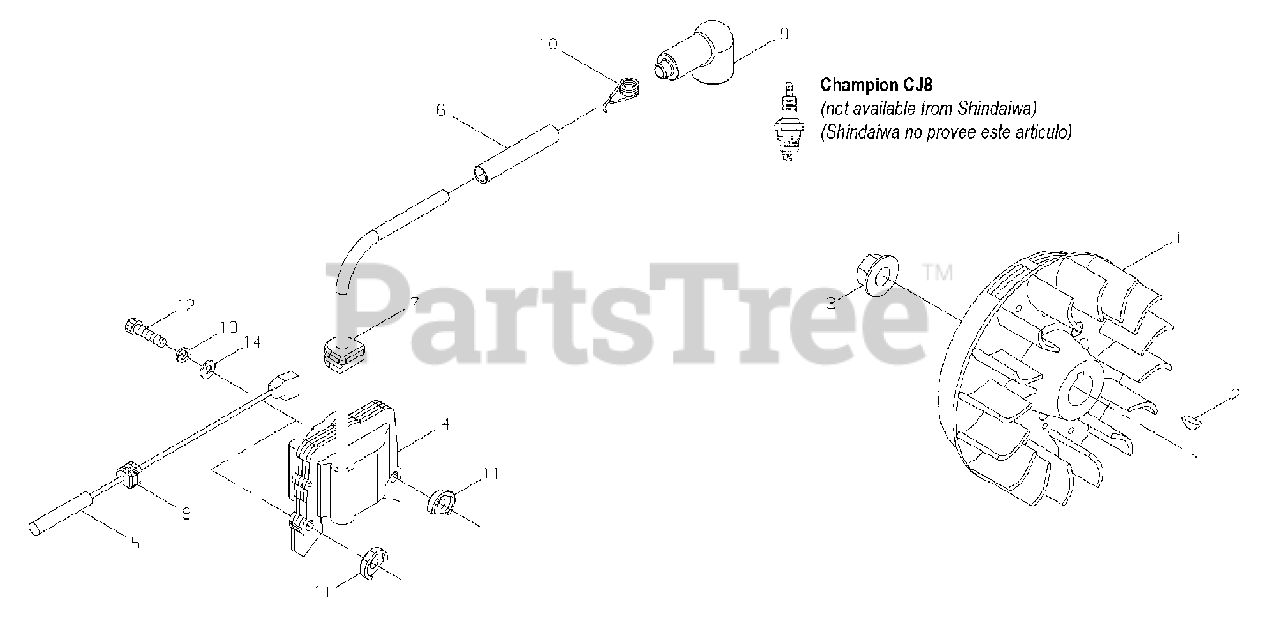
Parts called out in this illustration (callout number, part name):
1	FLYWHEEL
2	KEY - 3X10
3	NUT - 10 -- FLANGE
4	COIL, IGNITION
5	WIRE
6	TUBE
7	GROMMET
8	GROMMET
9	CAP, SPARK PLUG
10	TERMINAL, SPARK PLUG CAP
11	INSULATOR
12	SCREW - 4X24
13	LOCKWASHER - 4
14	WASHER
